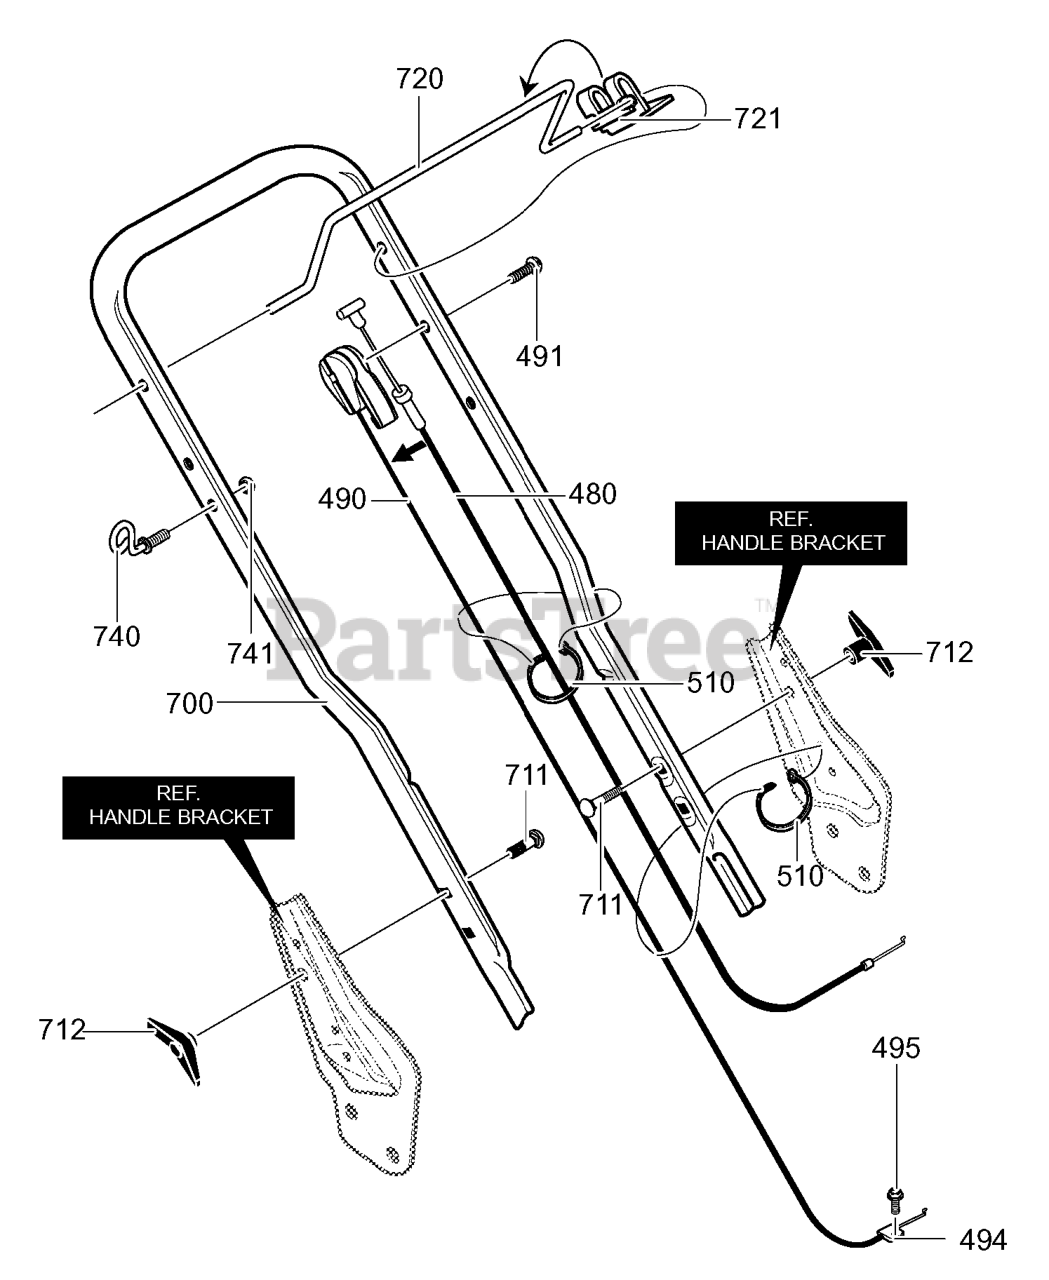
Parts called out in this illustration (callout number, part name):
480	CABLE, STOP
490	T-CABLE
491	SCREW, 1/4-20X2.00
494	CLAMP, THROTTLE
495	SCREW, 10-32X.62
510	CABLE TIE
711	BOLT, 5/16-18X2.00
712	KNOB, WING
720	LEVER, STOP FLAT
721	BRACKET, STOP LEVER
740	GUIDE, ROPE 1/4-20
741	NUT, 1/4-20
